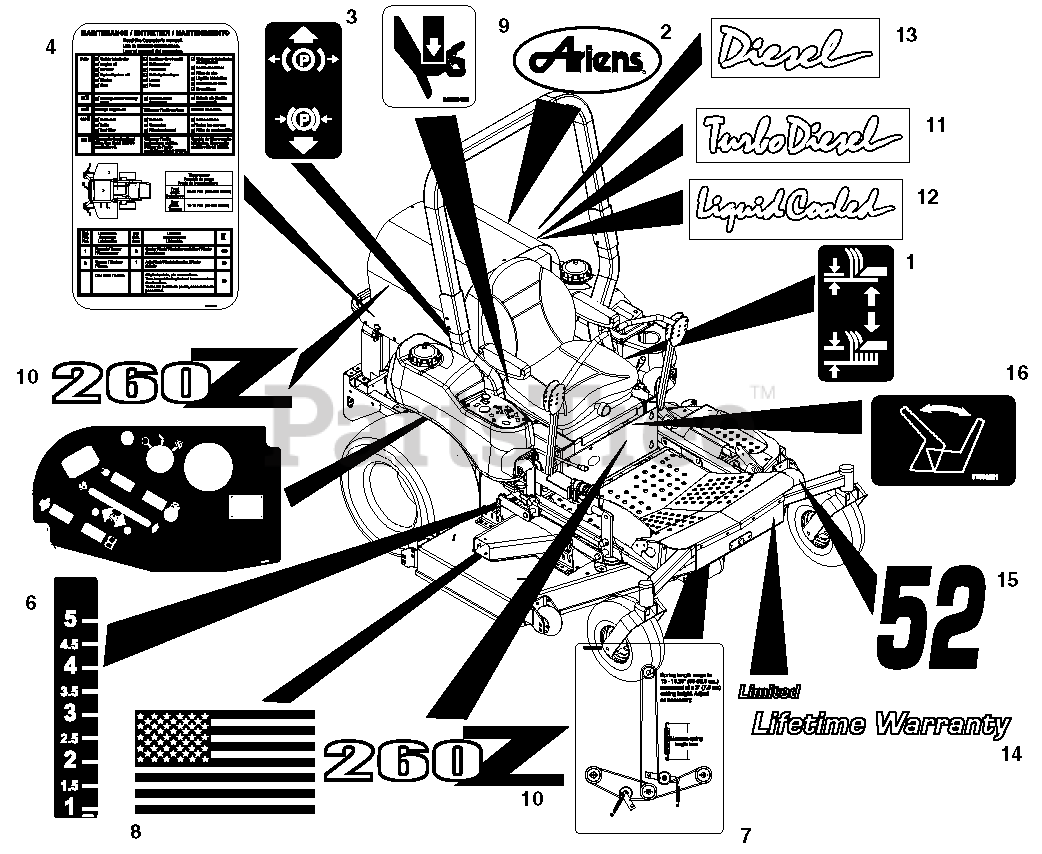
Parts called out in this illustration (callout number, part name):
1	Decal, Lift Lever
2	Decal, Ariens
3	Decal, Parking Brake Lever
4	Decal, Maintenance Instructions
5	Decal, Control Panel
6	Decal, Height of Cut
7	Decal, Belt Diagram
8	Decal, American Flag
9	Decal, Pinch Point
10	Decal, PM260Z (316, 317)
10	Decal, PM272Z (321)
10	Decal, PM252Z (322)
11	Decal, Turbo Diesel (317, 321)
12	Decal, Liquid Cooled
13	Decal, Diesel (316, 322)
14	Decal, Limited Lifetime Warranty
15	Decal, 60 (316, 322)
15	Decal, 72" (321)
15	Decal, 52 (322)
16	Decal, Seat Release
